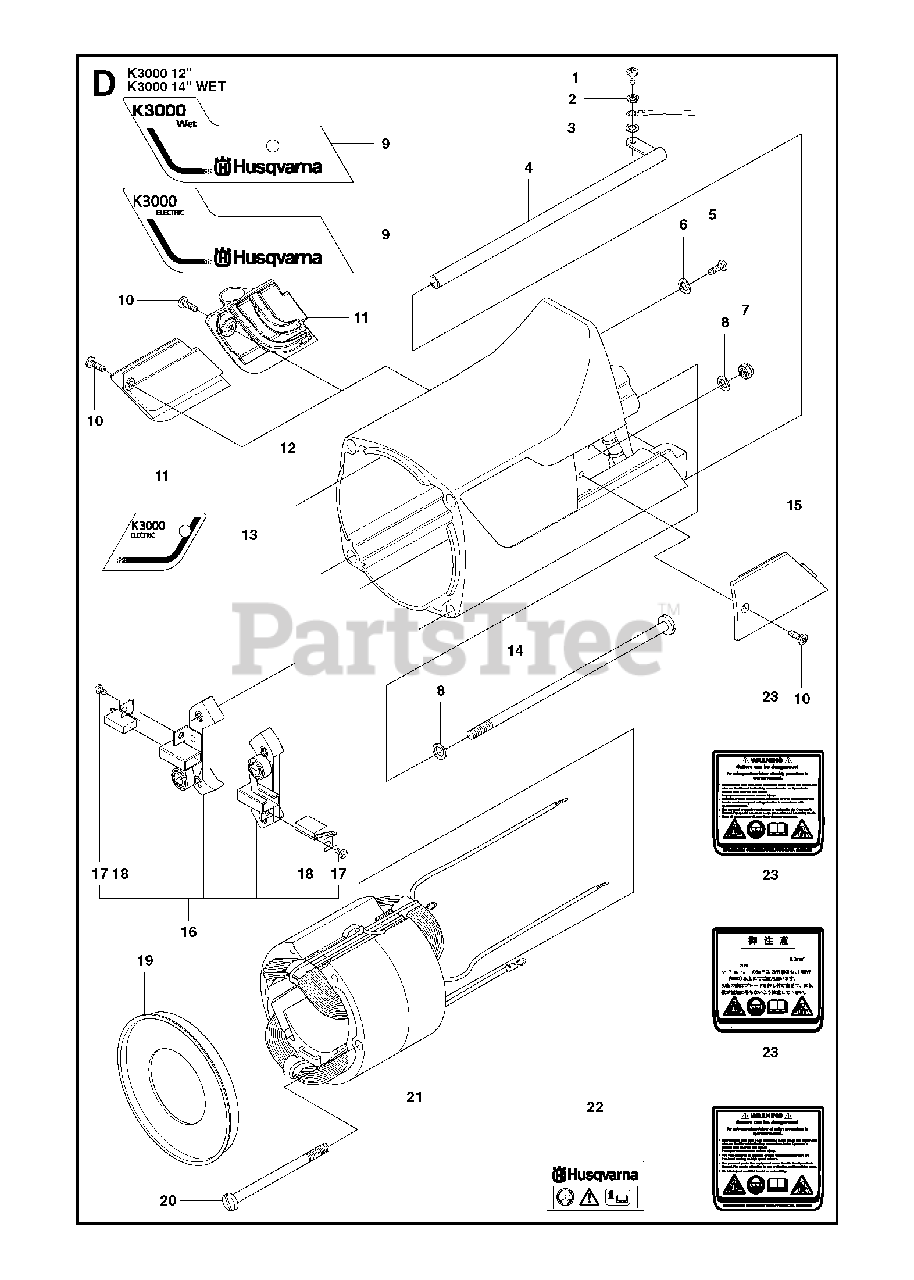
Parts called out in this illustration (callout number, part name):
1	SCREW CRPANM
6	SPRING WASHER
8	SPRING WASHER
9	LABELElectric
10	SCREW CCRPANT
12	MOTOR HOUSING
16	BRUSH HOLDERIncl. 17, 18
17	CARBON BRUSH
18	SCREW SLPANM
19	AIR STREAM DIRECTOR
21	STATOR ASSY100 - 120V
21	STATOR ASSY230V
23	LABELUSA
23	LABELUSA Wet
